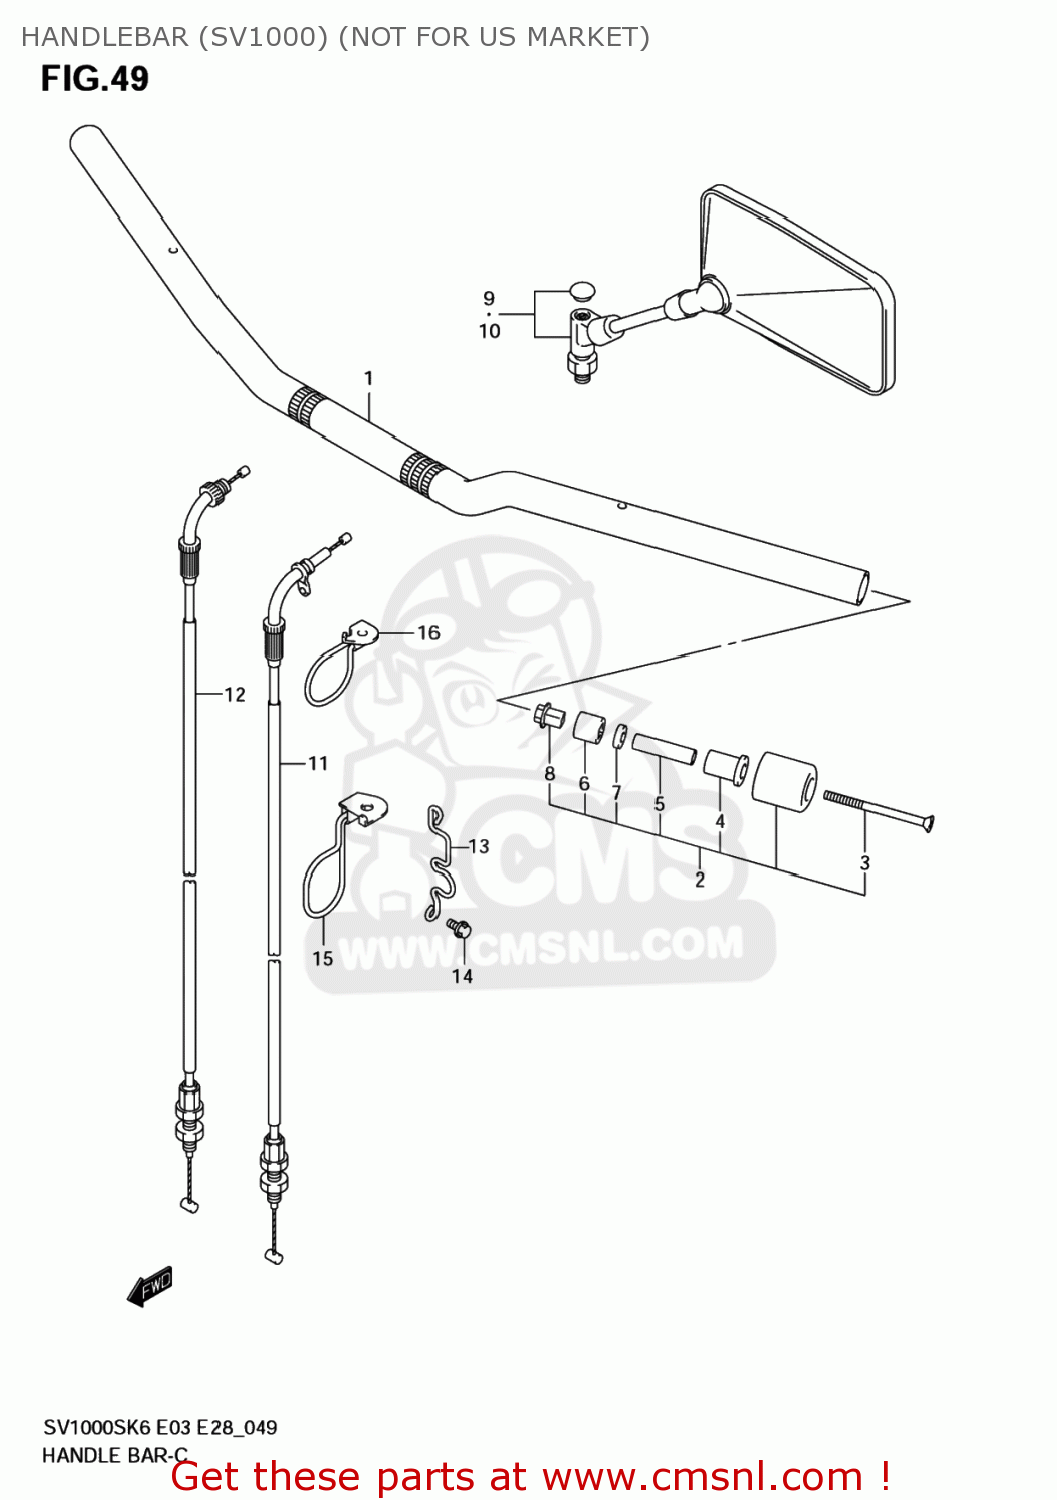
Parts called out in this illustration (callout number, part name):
1	HANDLEBAR
2	BALANCER SET,H
3	SCREW(6X110)
4	EXPANDER
5	SPACER,EXPANDER
6	EXPANDER,HANDLE BALANCER
7	WASHER(6.5X16X4)
8	NUT,HANDLE BAL
9	MIRROR ASSY,RE
10	MIRROR ASSY,RE
11	CABLE ASSY,THROTTLE NO.1
12	CABLE ASSY,THROTTLE NO.2
13	GUIDE,CABLE L
14	BOLT
15	GUIDE,THROTTLE CABLE
16	GUIDE,THROTTLE CABLE NO.2
